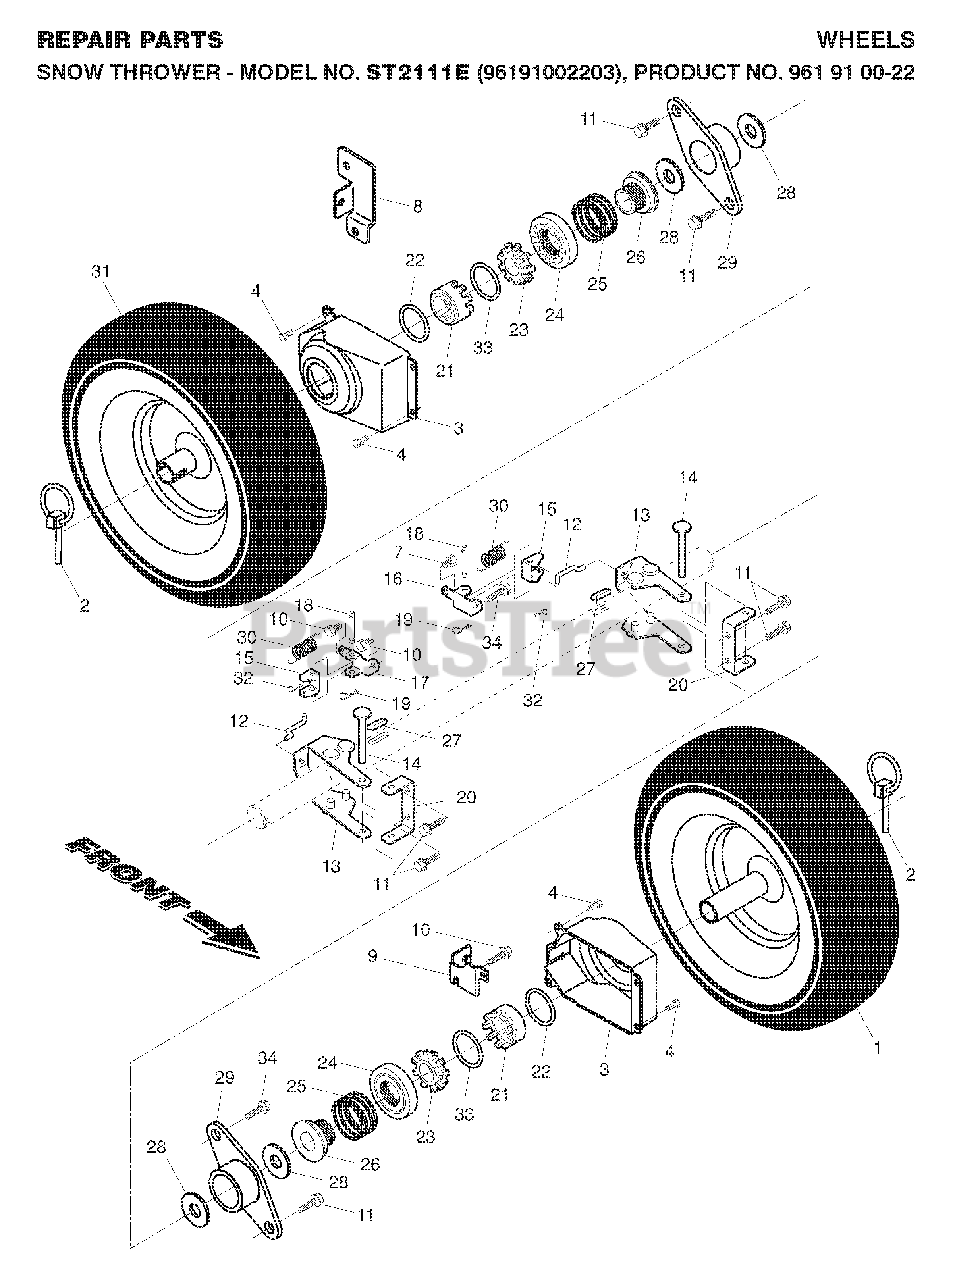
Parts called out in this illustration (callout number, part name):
1	16 X 4.8 LH WHEEL GREY
2	PIN KLIK, 1/4
3	COVER, POWER STEERING
4	SCREW, HEX HEAD, TAPPING
7	SCREW 14-20 X 5/8
8	BRACKET, STEERING CABLE RH
9	BRACKET.STEER.CABLE.LH.BZP
11	SCREW LT
12	LINK.STEER.YOKE
13	YOKE, STEERING
14	PIN, STEERING LEVER
15	BELLCRANK.STEER
16	CONTROL SHAFT
17	BRKT.STEER.PIVOT.RH
18	PIN, STEERING BELLCRANK
19	RETAINER CLIP PM
20	BRACKET.STEER.PNT.BLACK
21	DRIVER WHEEL
22	RING, WIRE RETAINER
23	LOBE WHEEL
24	SLIDE.CLUTCH
25	SPRING, CLUTCH SLIDE
26	LOBE.AXLE
27	KEY, SQUARE 1/4 X .875
28	WASHER TRUST 1"
29	BEARING, AXLE
30	SPRING LATCH
31	16 X 4.8 RH WHEEL
32	RETAINER CLIP
